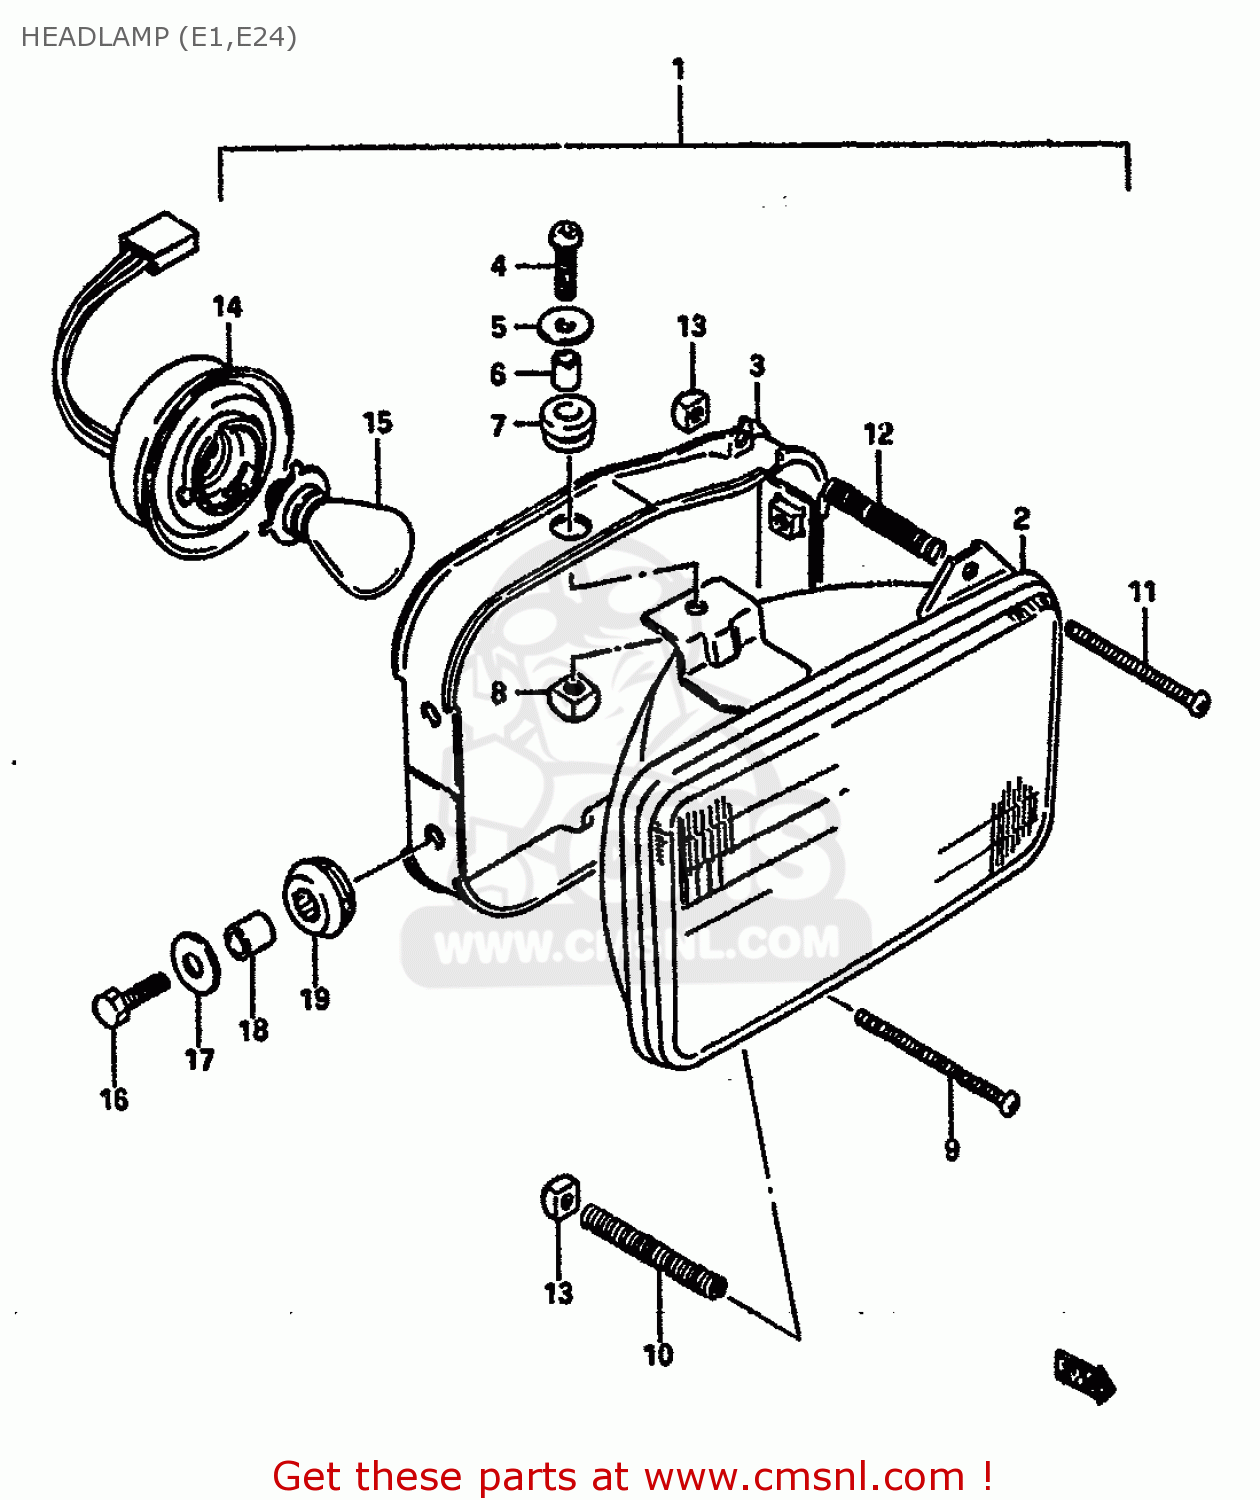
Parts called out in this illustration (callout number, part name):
1	HEADLAMP ASSY
2	UNIT
3	HOUSING
4	SCREW(5X14)
5	WASHER
6	SPACER
7	CUSHION
8	NUT
9	SCREW,HEADLAMP ADJUST
10	SPRING
11	SCREW,HEADLAMP ADJUST
12	SPRING
13	NUT
14	SOCKET,HEAD LAMP
15	BULB(12V45/45W,STANLEY,70281A)
16	BOLT
17	WASHER (6.5X20X1.2)
18	SPACER (6.1X9X9)
19	CUSHION
